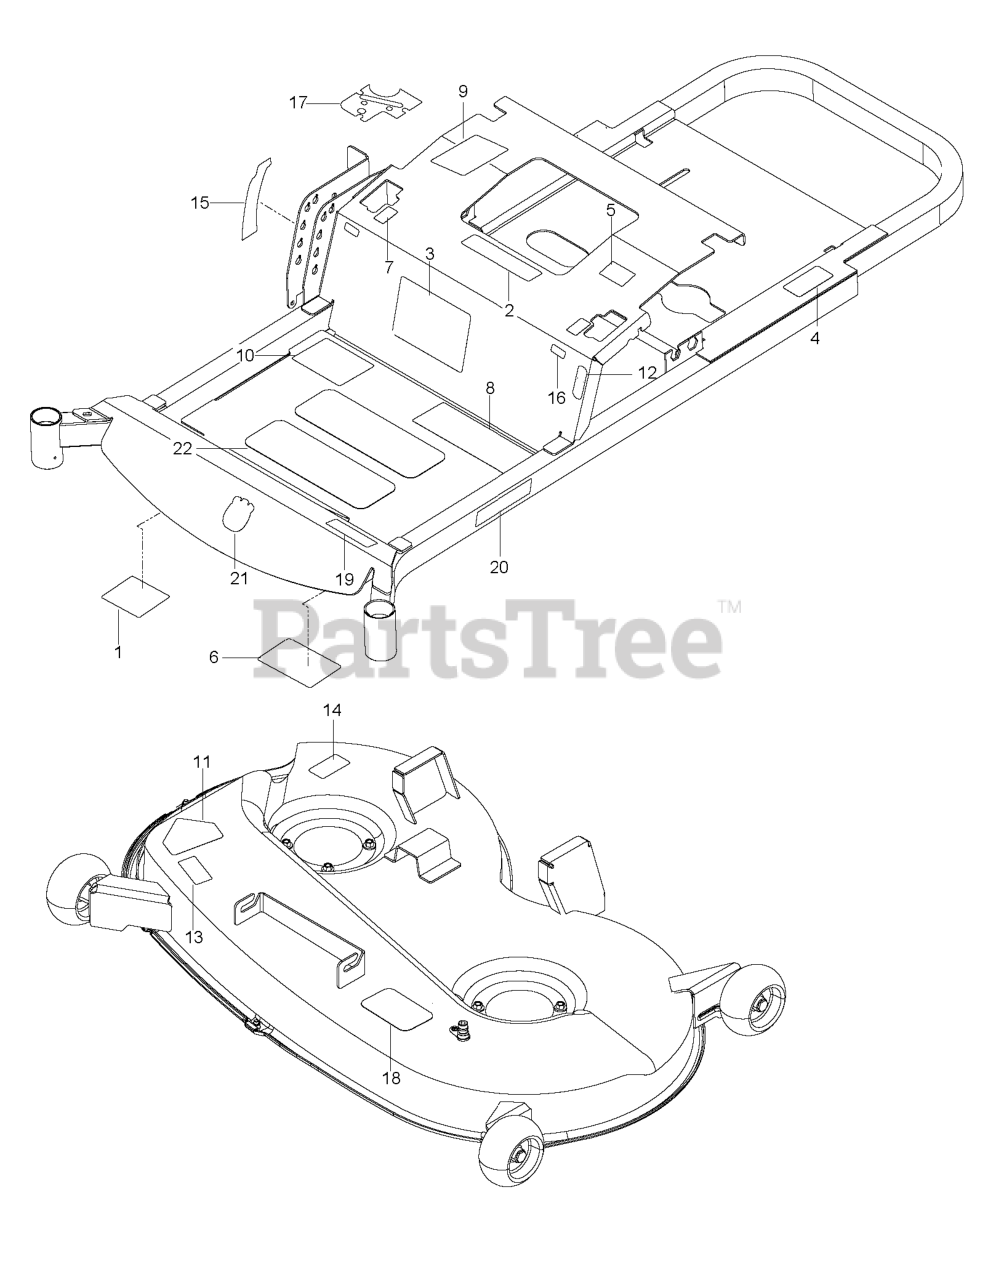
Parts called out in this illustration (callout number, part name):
1	DECAL, PROP. 65
2	EURO DECAL-BATTERY WARNIN6
3	DECAL, START
4	DECAL, DO NOT TOW
5	DECAL, EXITING MOWER
6	DECAL, SERVICE
7	DECAL, MOTION CONTROL
8	DECAL, SAFETY WARNING
9	DECAL, CUSTOMER RESPNSIBILITY
10	DECAL, WARNING
11	DECAL, CPSC
12	DECAL, PARK BRAKE
13	DECAL, EURO SEVERING
14	DECAL.DECK.6MIL./DEF.SHLD.WARN
15	DECAL, DECK HEIGHT, HUSQ
16	DECAL, F.S.T.
17	DECAL, CTRL PANEL, HUSQ
18	DECAL, BELT ROUTING
19	DECAL, RZ4623
20	RP.DECAL.BADGE.170MM.TEXTLOGO
21	DECAL.AUGER.HUSQ.CROWN.SNOW
22	ANTI-SKID PAD
